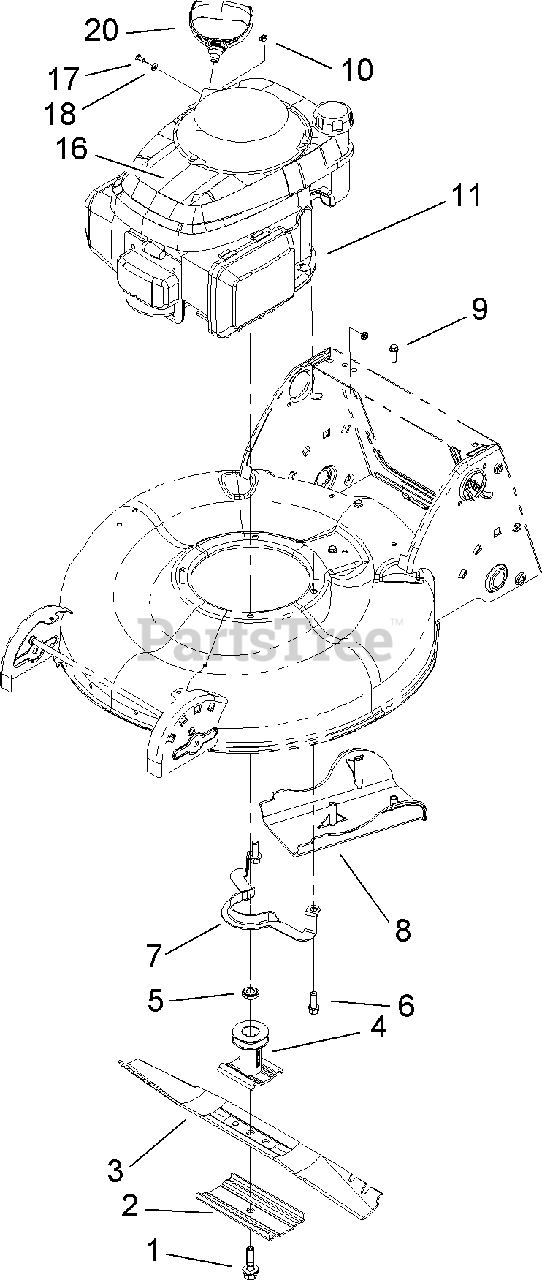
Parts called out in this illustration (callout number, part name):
1	BOLT-BLADE
2	SUPPORT-BLADE
3	BLADE-21 IN
4	BLADE DRIVER ASM
5	Spacer-Driver
6	SCREW
8	COVER-BELT
9	SCREW-HWH
10	STOP-ROPE
17	SCREW-METRIC
18	WASHER-FLAT
20	HANDLE-RECOIL
